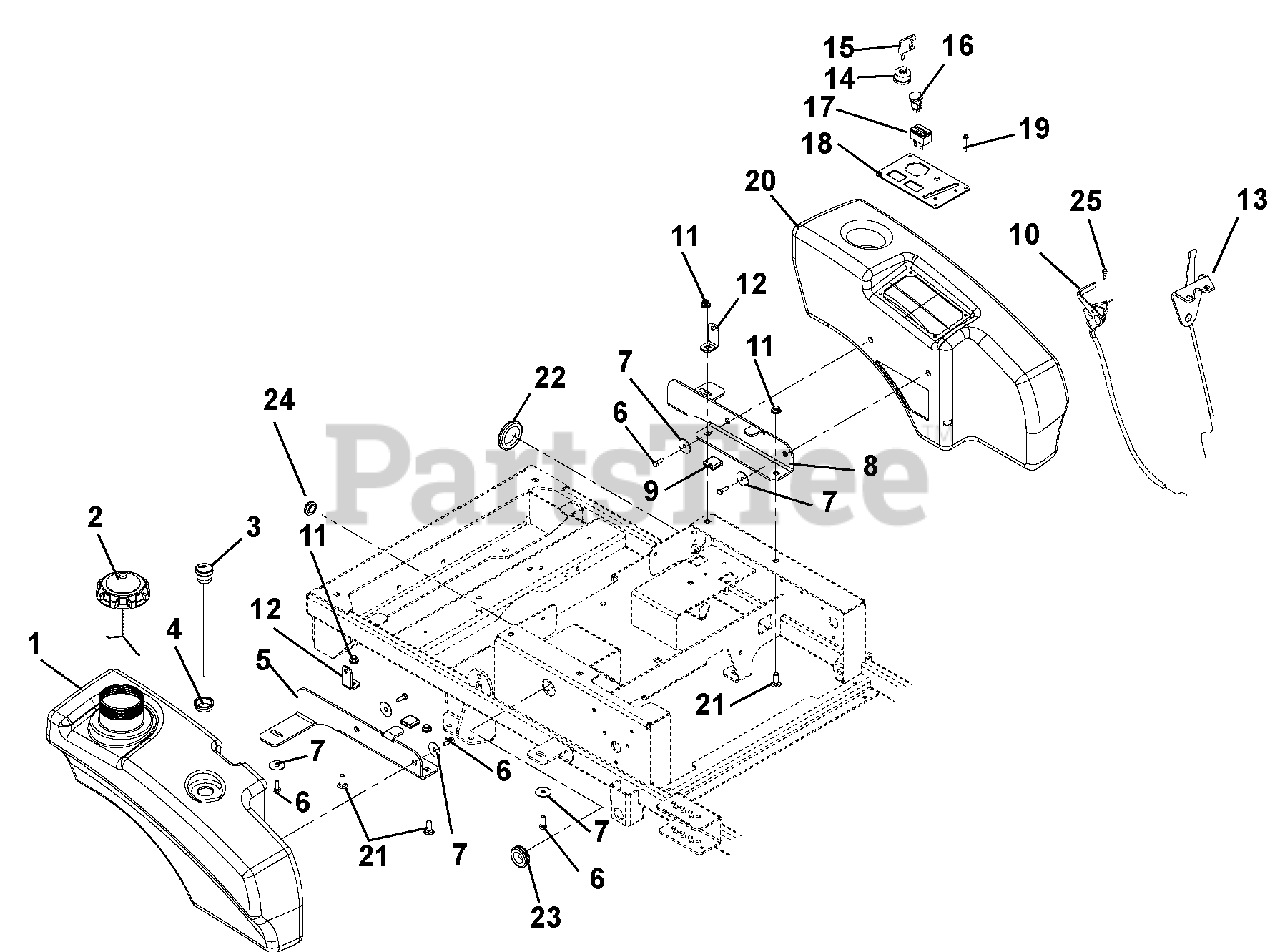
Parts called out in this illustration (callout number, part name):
1	KIT, XL TANK REPLACEMENT
2	CAP, FUEL
3	GAUGE, REMOTE FUEL 10.0"
4	GROMMET, FUEL GAGE
5	BRKT, RH REAR TANK MOUNT
6	BLT-SERHFWH .312-18X.50 YWZC
7	WSHR-FL-STL .347X1.254X.048YWZ
8	BRKT, LH REAR TANK MOUNT
9	GRIP, RUBBER (1.0X1.0X.187)BLK
10	CABLE-THROTTLE
11	@NUT-LK-NYL-FLG .38-16 YWZC
12	BRKT, HOOD PIVOT
13	CABLE, CHOKE
14	KEY SWITCH
15	KEY -W/CAP
16	SWITCH, CLUTCH
17	HOUR METER - DIGITAL
18	CONTROL PANEL
19	RIVET, PLASTIC .195 DIA.
20	FENDER, XL
21	@BLT-RDHDSQNK .38-16X1.00 G5YZ
22	GROMMET 1.70ID X 2.0OD
23	GROMMET 1.0ID X 1.38 OD
24	GROMMET,RUBBER 5/8 ID/1.13 OD
25	@SCR-TAP 10-24X.50 HWH TR YWZC
